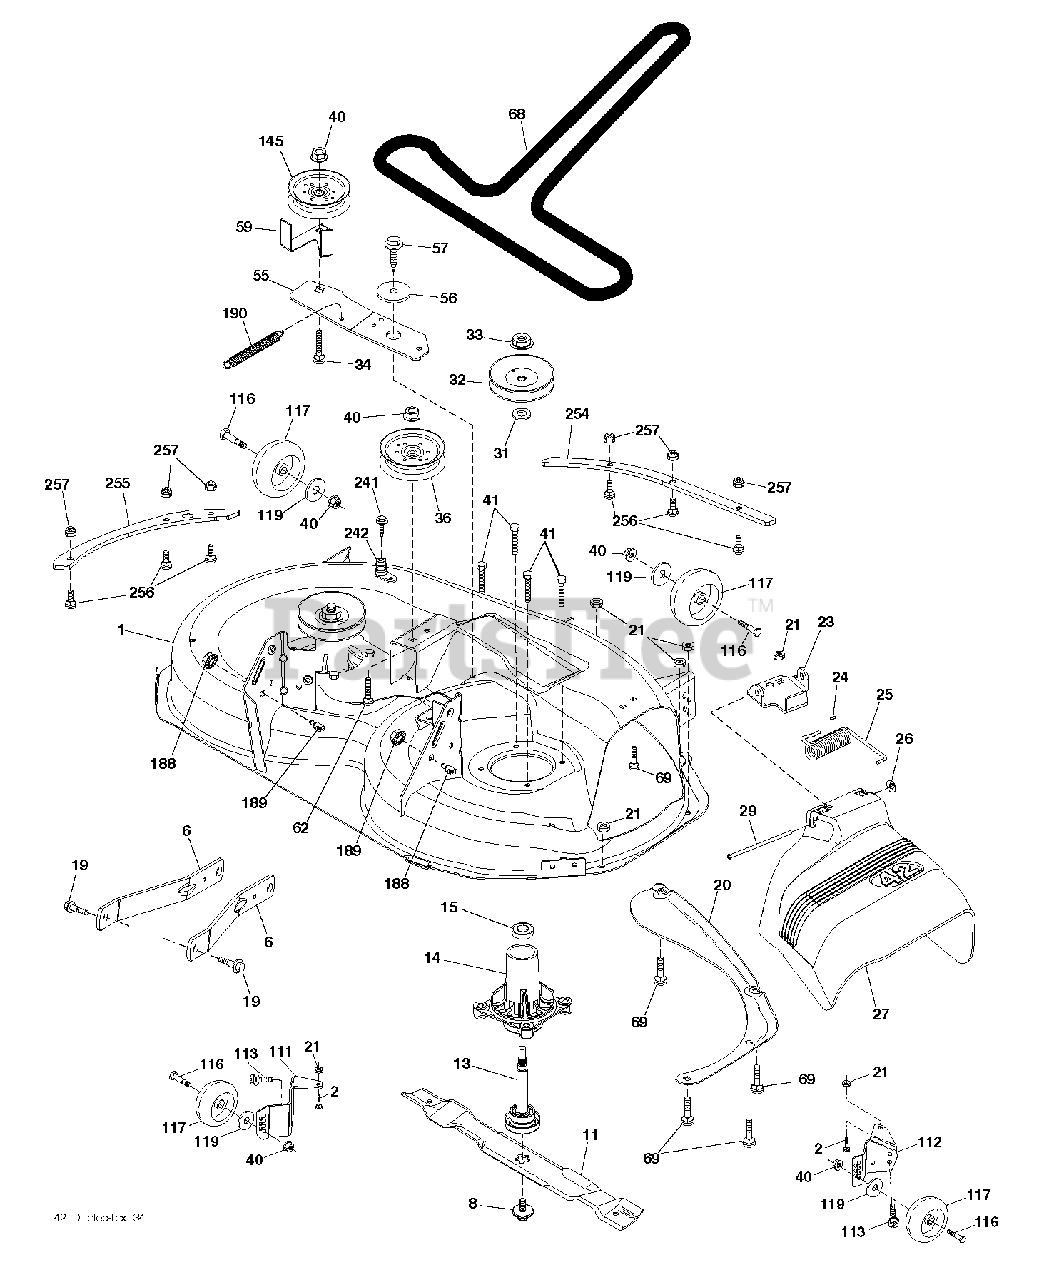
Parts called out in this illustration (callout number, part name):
1	DECK.SVC.42"2GW
2	BOLT 5/16-18 X3/4 ZN/YEL GR 5
6	ARM.SUSPENSION.MOWER.R
8	BOLT.WASHER.ASM.7/16-2
11	42" HI-LIFT BLADE
13	RB MANDREL.ASM.SUB-NON.GR
14	HOUSING.MANDREL.4PT.
19	BOLT.SHOULDER
20	BAFFLE.VORTEX
21	LOCKNUT
23	BRKT.DEFLECTOR.38"2005+
24	CAP-SLEEVE LT
25	SPRING.TORSION.DEFLECT
26	NUT PUSH M
27	SHIELD.DEFLECTOR.MOWER.42"BLAC
29	ROD.HINGE
31	WASHER.SPACER.MANDREL
32	PULLEY/MANDREL
33	NUT.FLANGE.LOCK.TOP
34	BOLT.3/8-16X1.50
36	PULLEY.IDLER.2006
40	NUT LOCK FLG 3/8-16 UNC
41	BOLT.HEX.WASHR.HED.313-18X1.19
55	IDLER.ARM.42"
56	SPACER.RETAINER
57	SCREW 3/8-16X1
59	GUARD, BELT
68	BELT V SECONDARY
69	BOLT
111	BRKT.WHEEL.GAUGE.LH.42"
112	BRKT.WHEEL.GAUGE.RH.42"
113	BOLT.5/16HEX.WHS.HD
116	BOLT M
117	WHEEL.GAGE.HALF.SPOKED
119	WASHER
145	PULLEY.IDLER.48"PRIMARY
188	STUD.FASTNER.W/ANTI-ROTATE
189	NUT LOCK HEX FLANGE 5/16-18
190	SPRING.MOWER.DRIVE.ELECTRIC
241	SCREW.TT.#10-32X.5.3/8.FLANGE
242	PORT.WASHOUT
254	PLATES.RENFRC.42DECK.PT431FRNT
255	PLATES.RENFRCE.42DECK.X431SIDE
256	RHSNB, 1/4-20 X 1, GR5
257	NUT T
